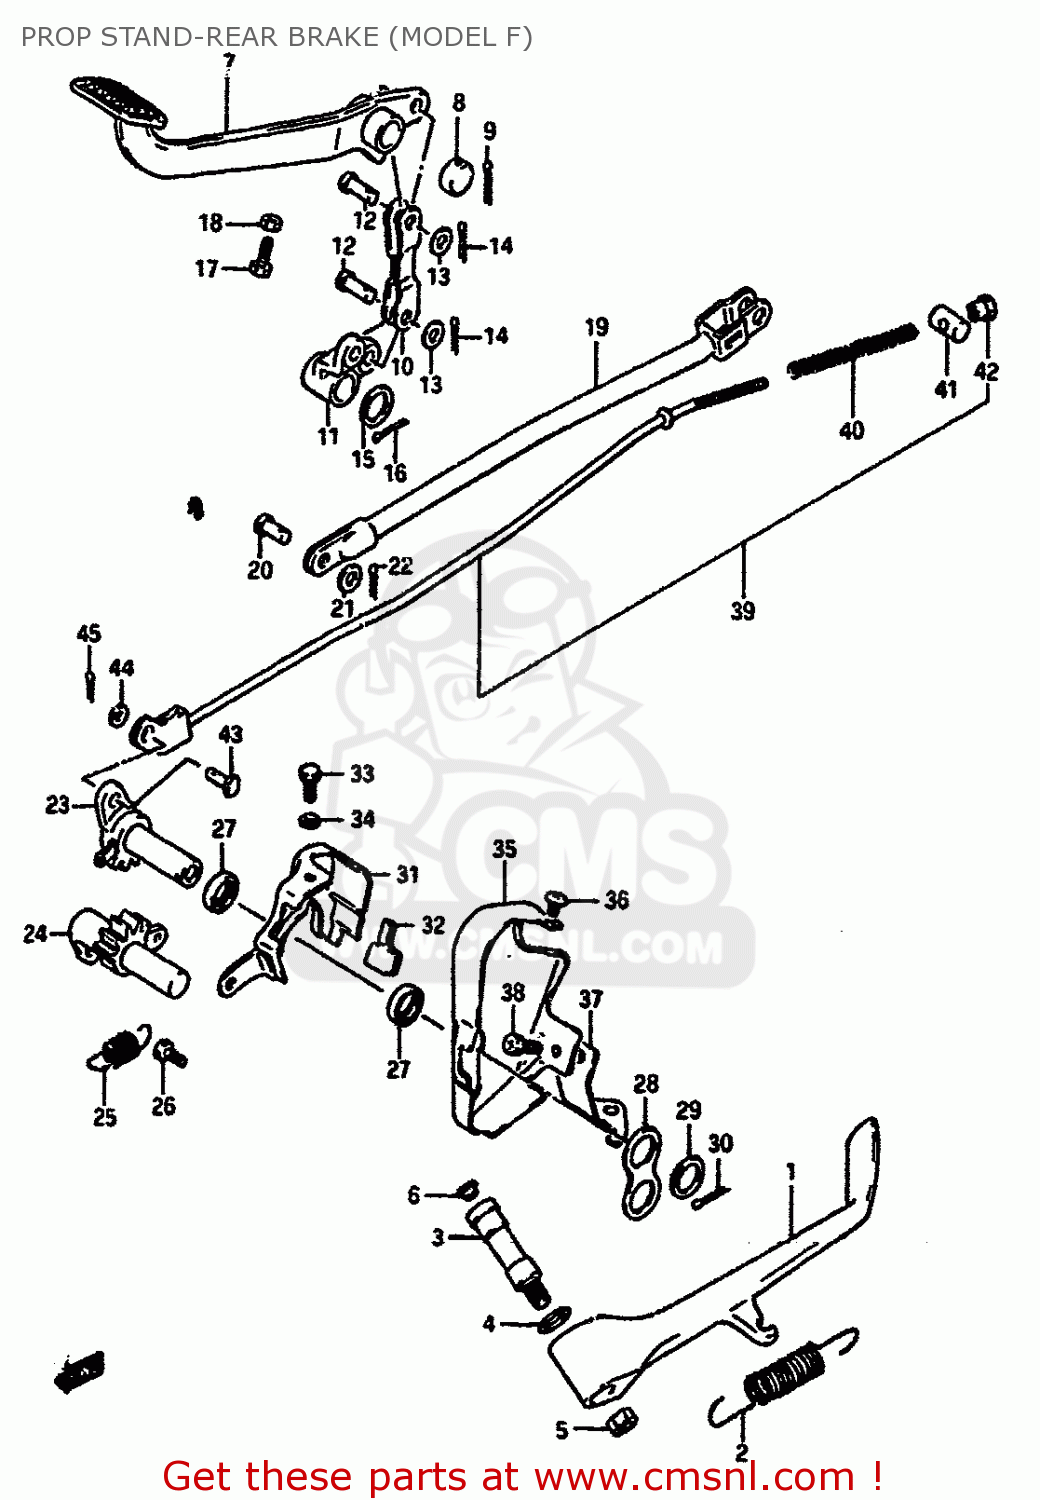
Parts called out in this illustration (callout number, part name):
1	STAND,PROP
2	SPRING
3	BOLT,PROP STAND
4	THRUST WASHER
5	NUT
6	CAP
7	PEDAL ASSEMBLY,BRAKE
8	CAP,BRAKE PEDAL
9	COTTER PIN
10	LINK COMP,BRAKE ROD NO
11	ARM,BRAKE PEDAL LINK
12	PIN
13	WASHER
14	PIN
15	WASHER (16.5X42X2.6)
16	COTTER PIN
17	BOLT
18	NUT 6MM
19	LINK COMP,BRAKE NO.2
20	PIN
21	WASHER
22	PIN
23	ARM COMP,BRAKE ROD
24	ARM COMP,BRAKE PEDAL,LEFT
25	SPRING
26	ARM,BRAKE PEDAL LINK
27	SEAL
28	PLATE,BRAKE PEDAL ARM
29	WASHER (17.2X30X1.6)
30	COTTER PIN
31	COVER COMP,BRAKE ROD ARM
32	GROMMET,BRAKE COVER
33	BOLT
34	WASHER,LOCK
35	COVER,BRAKE ROD ARM
36	SCREW
37	BRACKET COMP,BRAKE ROD AR
38	SCREW(6X10)
39	ROD ASSEMBLY,REAR BRAKE
40	SPRING
41	PIN
42	NUT (6MM)
43	PIN
44	WASHER
45	PIN 20X20
